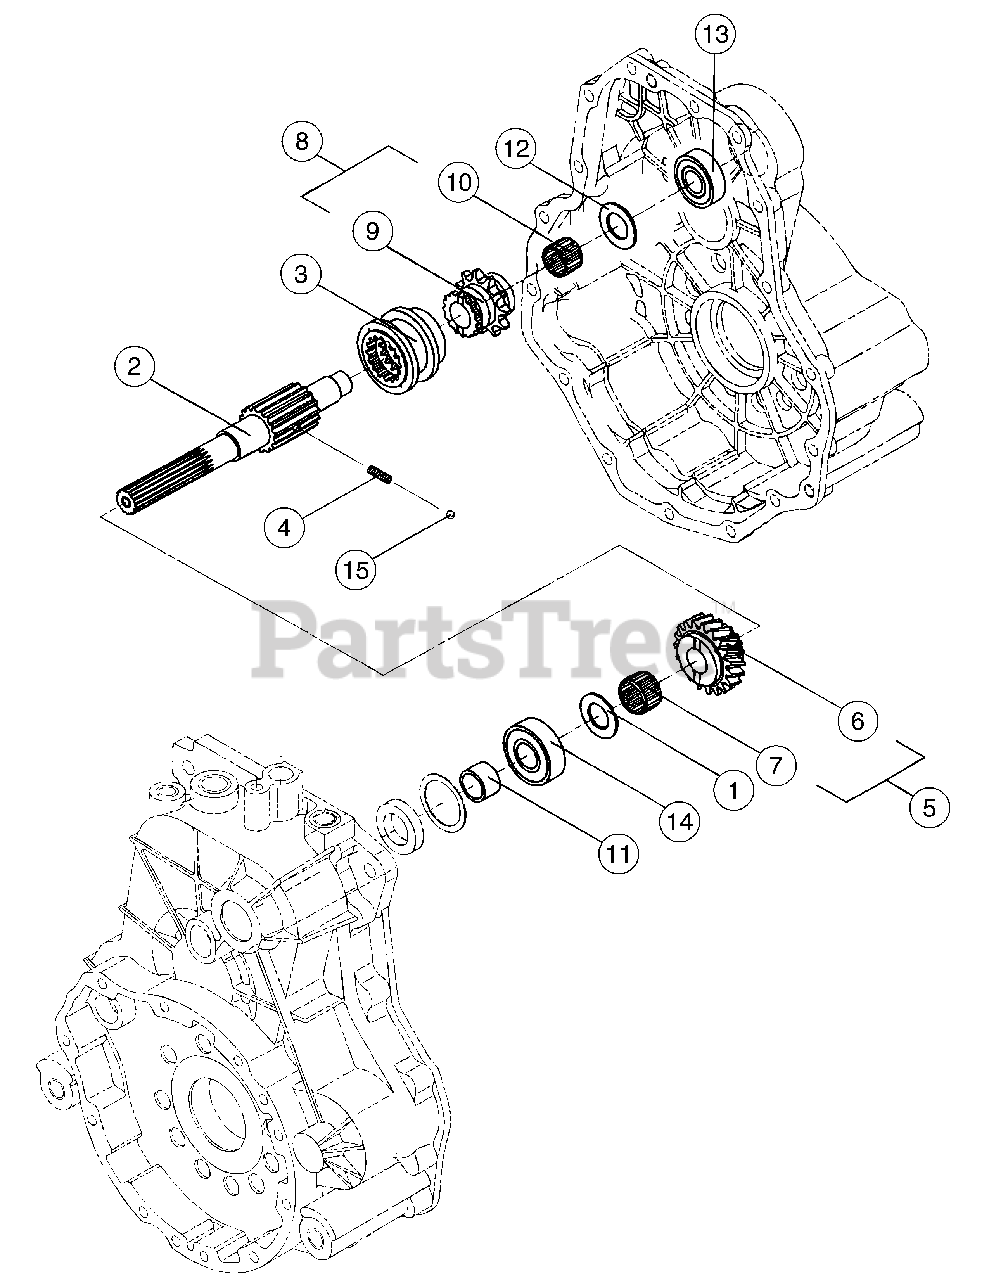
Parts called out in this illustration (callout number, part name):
3	Shifter
4	Spring 29.5
4	Spring 18
5	Gear Asm
8	Sprocket Asm
15	Bearing Ball, 1/4
